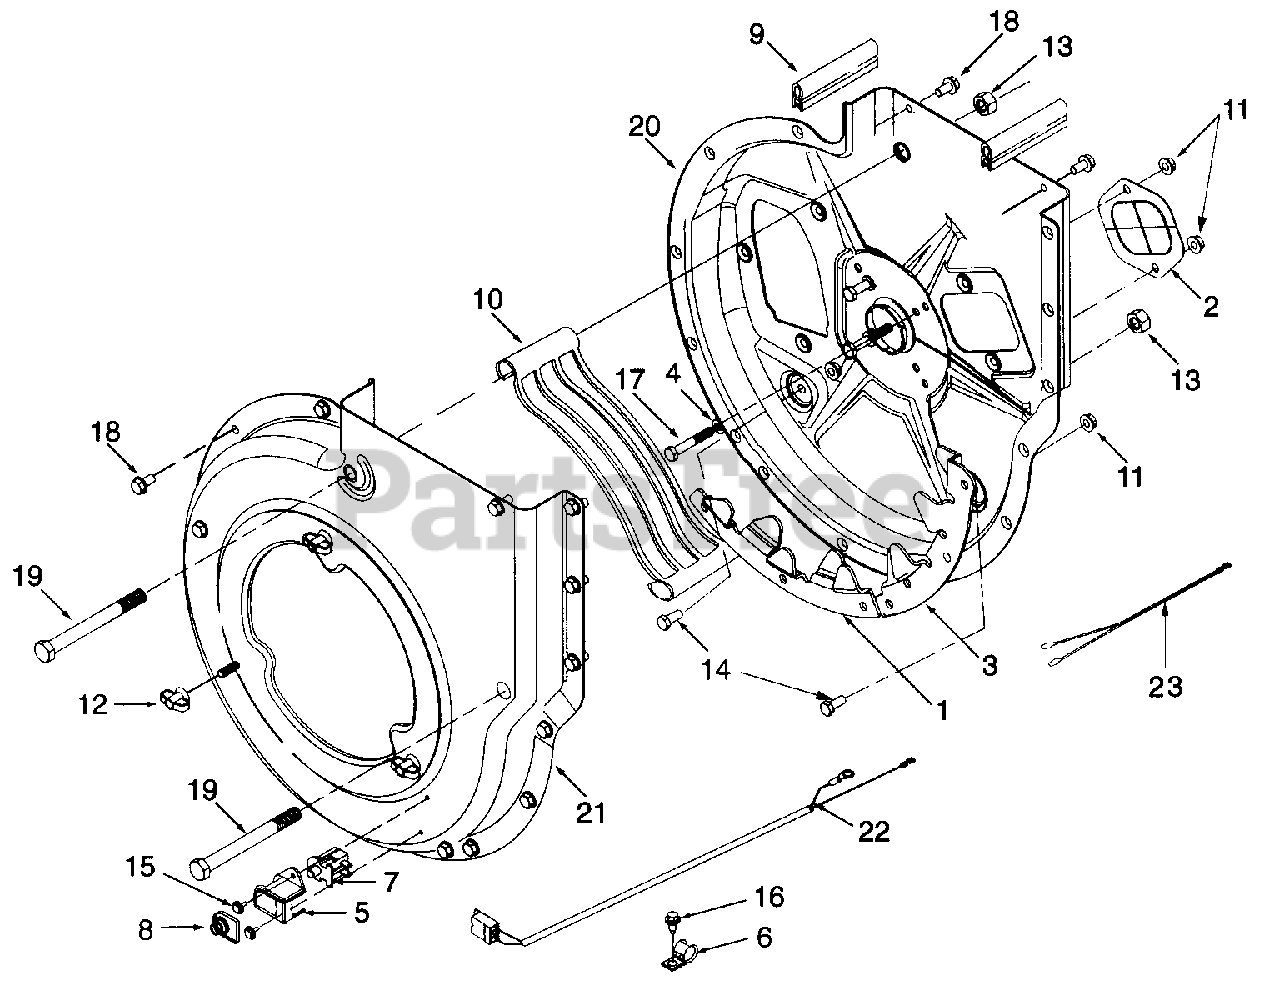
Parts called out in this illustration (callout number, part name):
4	Washer, Lock, 5/16
5	Cover, Safety Switch Mtg
7	Switch, Snap Mount
8	Cover, Switch
9	Rubber Seal
10	Screen, Discharge
11	Nut, Hex Flange Lock, 5/16-18
12	Knob, 5/16-18
13	Nut, Hex Center Lock, 1/2-13
14	Screw, Hex Cap, 5/16-18 x .75GR5
15	Screw, Wash Hd Tapp #10-16
16	Screw, Wash Hd Tapp 1/4-14
17	Screw, Hex Cap, 5/16-18 x 2 GR5
18	Screw, Wash Hd Tapp 5/16-18
19	Screw, Hex Cap, 1/2-13 x 5.0
22	Harness, Wire
23	Adapter, Harness
